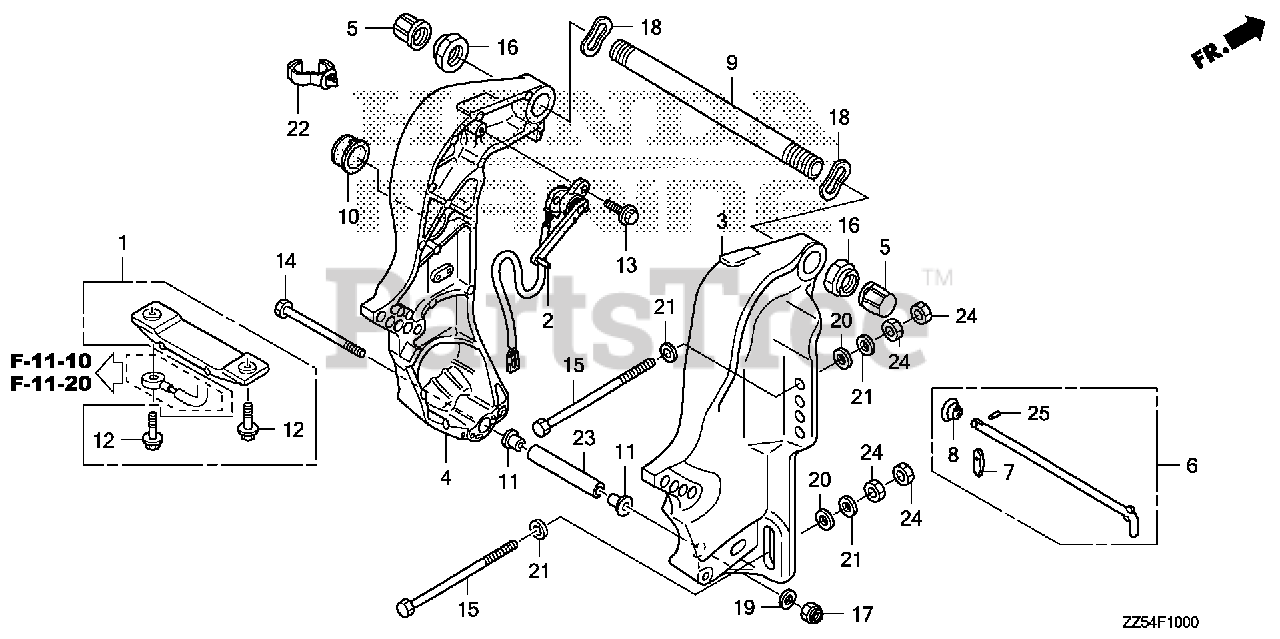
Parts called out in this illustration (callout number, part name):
1	METAL KIT, ANODE
2	SENSOR ASSY., TRIM ANGLE
3	BRACKET, R. STERN *NH282MU* (OYSTER SILVER METALLIC-U)
4	BRACKET, L. STERN *NH282MU* (OYSTER SILVER METALLIC-U)
5	CAP, TILTING BOLT
6	ROD, ADJUSTING
7	STOPPER, ROD
8	SPRING, ADJUSTING ROD
9	SHAFT, TILTING
10	BUSH, MOTOR CODE
11	BUSH, CYLINDER (LOWER)
12	BOLT, FLANGE (6X23)
13	BOLT, FLANGE (6X20)
14	BOLT, HEX. (10X158)
15	BOLT, HEX. (12X100)
15	BOLT, HEX. (12X119)
16	NUT, SELF-LOCK (7/8-14UNF)
17	NUT, SELF-LOCK (10MM)
18	WASHER, WAVE (22MM)
19	WASHER, PLAIN (10MM)
20	WASHER, PLAIN (12MM)
21	WASHER, PLAIN (12MM)
22	CLIP, WIRE HARNESS
23	COLLAR, DISTANCE (10X90)
24	NUT, HEX. (12MM)
25	PIN, SPRING (2.5X8)
